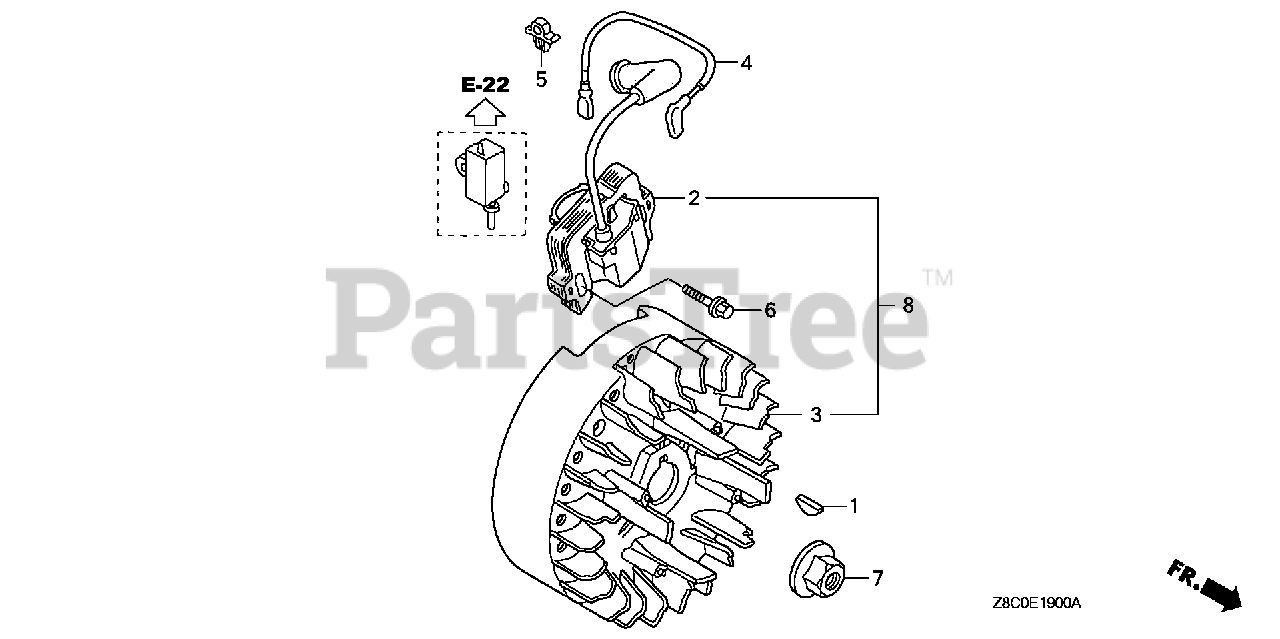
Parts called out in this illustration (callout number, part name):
1	KEY, SPECIAL WOODRUFF (25X18)
2	COIL ASSY., IGNITION (USE FOR F/W OF TEC) (TEC)
2	COIL ASSY., IGNITION (PHELON) (USE FOR F/W OF PHELON)
2	COIL ASSY., IGNITION (PHELON)
3	FLYWHEEL COMP. (PHELON) (USE FOR IGN. COIL OF PHELON)
3	FLYWHEEL COMP.(TEC) (USE FOR IGN. COIL OF TEC)
4	WIRE, STOP SWITCH
5	HOLDER, STOP SWITCH WIRE
5	HOLDER, WIRE (FASTEX)
6	BOLT, FLANGE (6X20) (CT200)
7	NUT, FLANGE (14MM)
8	FLYWHEEL KIT (SEL)
